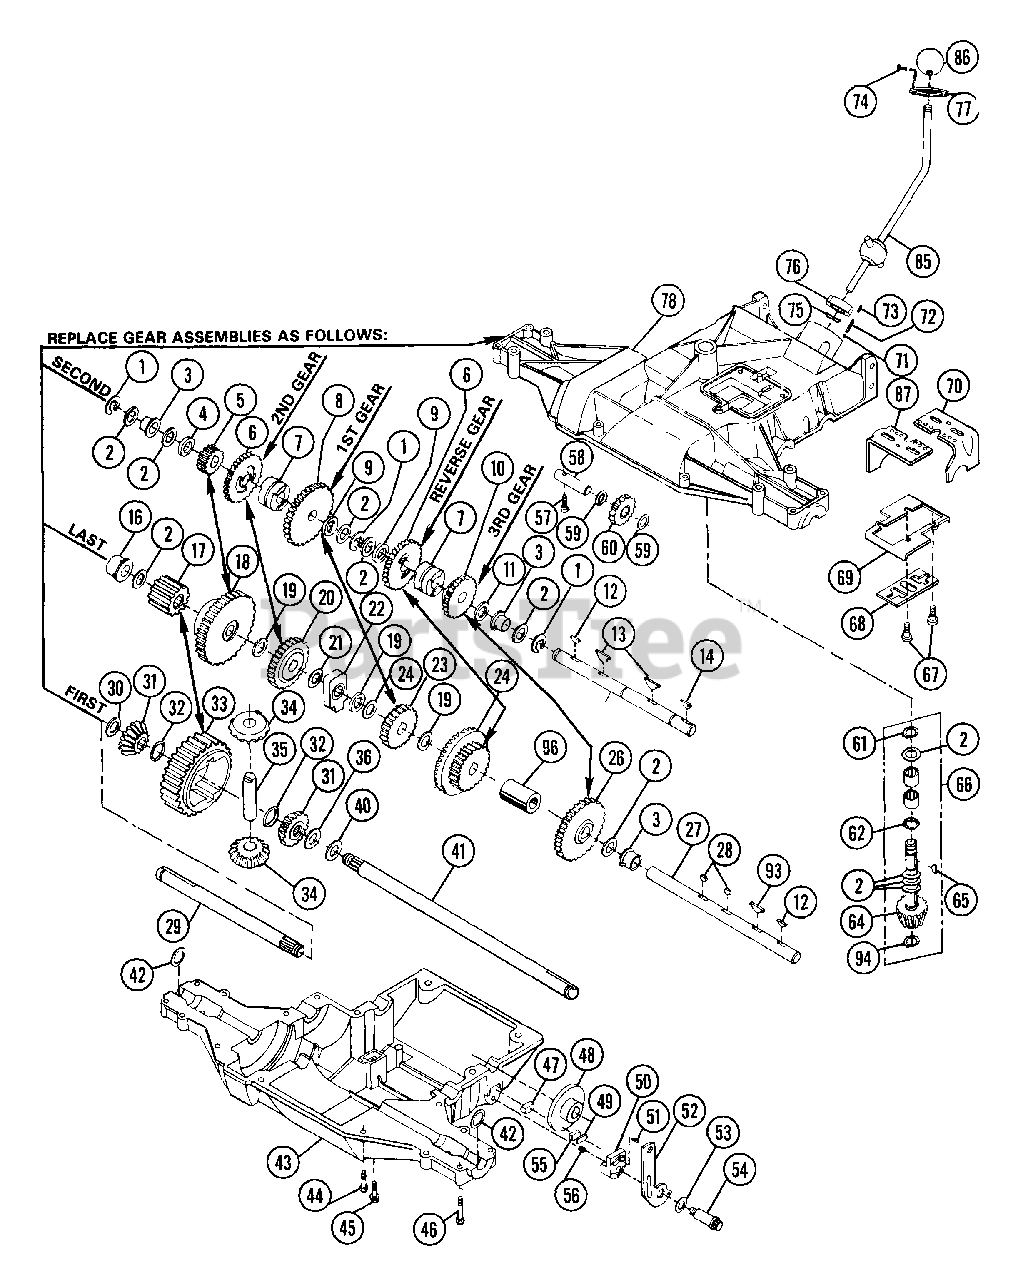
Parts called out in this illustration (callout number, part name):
1	RG-RTNG-EXT .625X.042
2	SHIM KIT
3	FLANGE BEARING
4	SPACER .630X1.000X.110
5	SPUR GEAR 13T
6	SPUR GEAR 20T
7	CLUTCH COLLAR
8	SPUR GEAR 33T
9	SPACER .633X1.00X.260
10	SPUR GEAR 25T
11	WASHER
12	KEY-WDRF .125X.500X.203 SAE 3
13	KEY-FTHR FOOTE #3068
14	KEY-WDRF .188X.625X.25 SAE 61
15	INTERMEDIATE SHAFT
16	FLANGE BEARING
17	GEAR ASSY 12T
18	SPUR GEAR 37T
19	WASHER
20	SPUR GEAR 25T
22	SHAFT SUPPORT ASSY
23	SPUR GEAR - 17 T
24	DRIVE SHAFT
26	SPUR GEAR 30T
27	DRIVE SHAFT
28	KEY-WDRF FOOTE #3311
29	L H AXLE
30	SHIM KIT
31	SPLINED MITER GEAR 15T
32	RG-RTNG-EXT .625X.035
33	SPUR GEAR 32T
34	MITER GEAR 15T
35	CROSS SHAFT
36	WSHR-HDND-THRST .758X1.23X.031
40	WSHR-FL-STL .760X1.250X.060 PL
41	R H AXLE
42	SEAL J.B.FOOTE #5130
43	LOWER HOUSING
44	SCR-TAP .250-20X.860 HH
45	SCR-MCH 12-24X.62 HEXWH
46	BLT-HEX .25-20X1.25 PL GR5
47	BRAKE JAW FRICTION PUCK
48	BRAKE DISC
49	SPACER - FLAT .045 THICK
50	BRAKE JAW ASSY
51	SCR-SET 8-32 FOOTE 1606
52	ACTUATING LEVER ASSY
53	SHIM KIT
54	SHOULDER BOLT
55	FRICTION PAD
56	SG-COMP J.B. FOOTE
57	SCR-MCH 10-24X1.00 HEX PL
58	IDLER SHAFT
59	WSHR-FL-STL .505X1.000X.020
60	IDLER GEAR ASSY
61	RG-RTNG-EXT .625X.035
62	O-RING .612X.805X.102
65	KEY-WDRF .188X.75X.313 SAE 9
66	INPUT SHAFT ASSY KIT
67	BLT-HEX .25-28X.75 PL GR5
68	LOCK-OUT PLATE
69	FORK PLATE SUPPORT
70	SHIFTER FORK
71	DETENT BALL
72	SG-COMP ??X??X?? FOOTE
73	SCR-SET .25-20X.38 SKHCUP OH
74	SCR-TAP 10-24X.484 HWH TR
75	WAVE WASHER .760X1.062X.105FH
76	NYLON INSERT
77	NYLON COVER
78	UPPER HOUSING
85	SHIFT LEVER ASSY
86	SHIFT BALL
87	SHIFTER FORK
93	KEY-WDRF .188X.75X.313 SAE 9
94	RG-RTNG-EXT .500X.035
95	WASHER .030 THK
95	WSHR-FL-STL .505X1.000X.020
96	SPACER-J.B. FOOTE SERVICE
